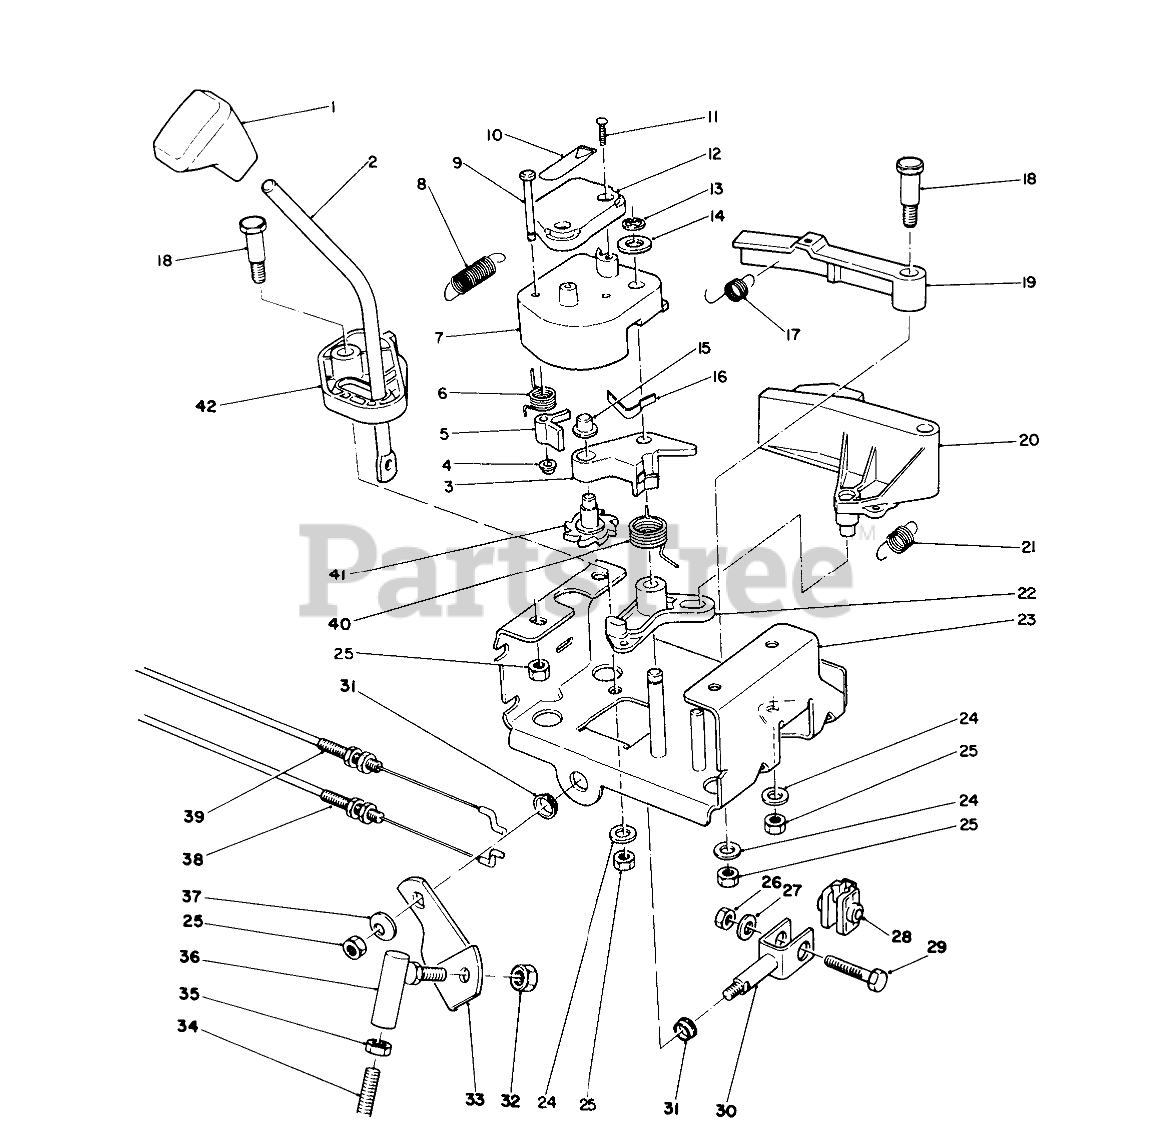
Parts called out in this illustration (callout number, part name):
1	KNOB-SHIFT
2	ROD-SHIFT
3	LEVER-WHEEL, INDEX
4	NUT-PUSH
5	TANG-INDEX
6	SPRING-TORSION
7	LATCH-LEVER
8	SPRING-EXTENSION
9	PIN-TANG
10	DECAL
11	SCREW-PPH
12	COVER-LATCH
13	RING-RETAINING
14	WASHER-THRUST
15	RETAINER-PUSH ON
16	SPRING-FLAT
17	SPRING-EXTENSION
18	SCREW-SHOULDER
19	LEVER-LOCKOUT
20	LEVER-REVERSE
21	SPRING-EXTENSION
22	LEVER-REVERSE, SWITCH
23	Frame-Control
24	WASHER-PLAIN
25	NUT-LOCK, NI
26	NUT-LOCK, NI
27	WASHER-FLAT
28	RETAINER-ROD, SHIFT
29	CAPSCREW
30	CLEVIS ASM
31	BUSHING
32	NUT-LOCK, NI
33	BRACKET-SHIFT
34	ROD-BENT SHIFT, LOWER
35	NUT-HJ
36	JOINT-BALL
37	WASHER-BELLEVILLE
38	CABLE-GEARBOX
39	CABLE-ARM, LATCH
40	SPRING-TORSION
41	WHEEL-INDEX
42	BASE-LOCKOUT
